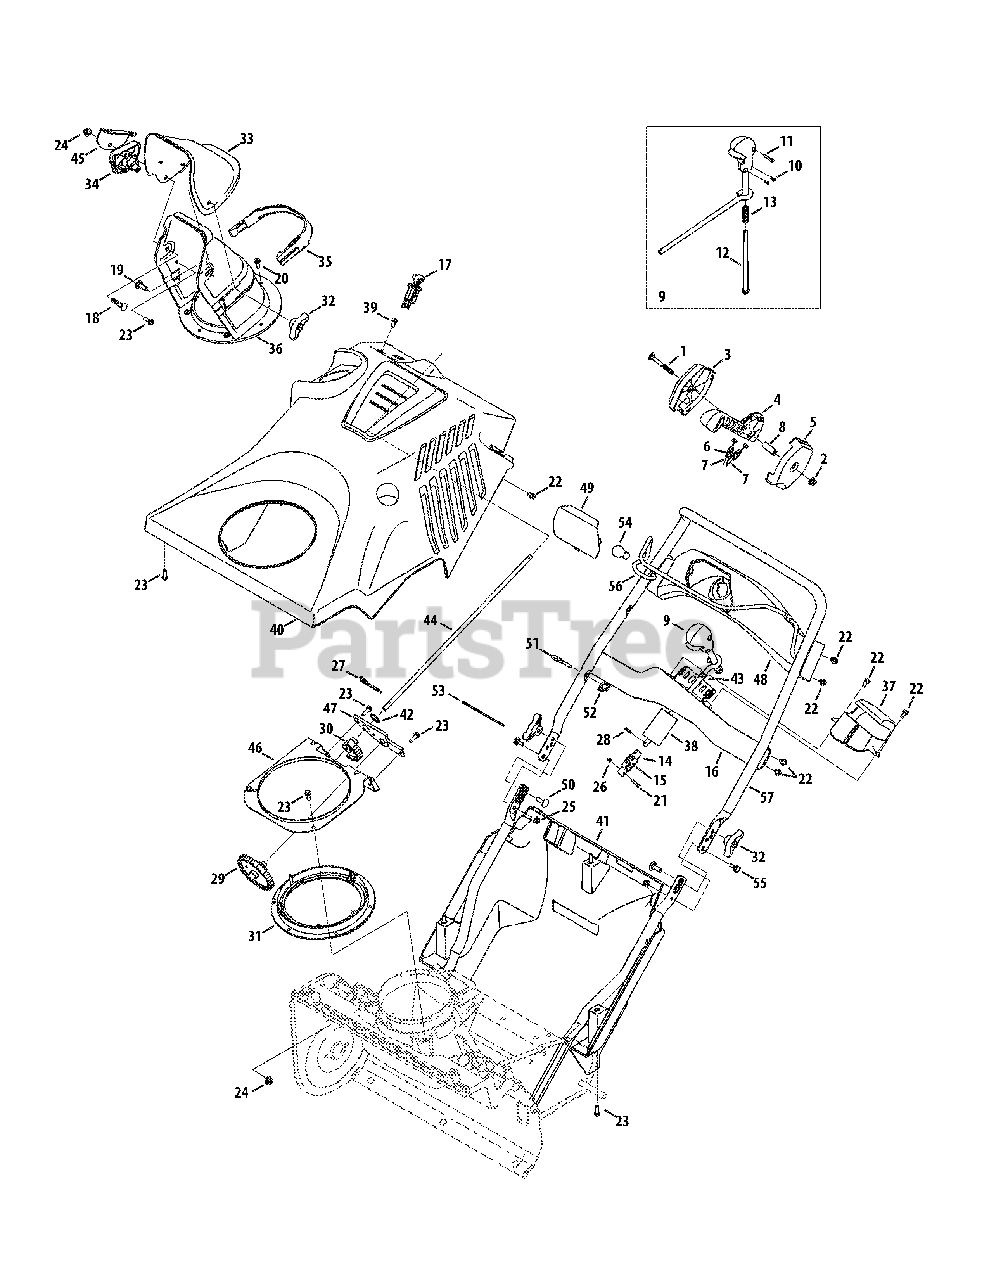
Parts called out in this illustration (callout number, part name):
1	Carriage Bolt, 5/16-18 x 2.5
2	Flange Lock Nut, 5/16-18
3	Chute Control Panel
4	Cable Handle Guide
5	Chute Control Panel, Inner
6	Cable Clip
8	Spacer, .325 ID x .496 OD x 1.34
9	Chute Control Assembly
10	Screw, #6 x .375
11	Screw, #8 x 1.00
12	Chute Rod
13	Spring, .460 OD x 1.469
14	Joint Block Assembly
15	Roll Pin, 3/16 Dia. x 1.1 LG.
16	Indicator Bracket Assembly
17	Ignition Switch Assembly
18	Carriage Bolt, 5/16-18 x 1.00
19	Carriage Bolt, 5/16-18 x .75
20	Hex Washer Screw, 1/4 x .750
21	Screw, #8-32 x .875
22	Hex Washer Screw, 1/4-20 x .625
23	Screw, Hi-Lo:1/4-15, 0.75
24	Flange Lock Nut, 5/16-18
25	Flange Lock Nut, 1/4-20
26	Hex Lock Nut, #8-32
27	Cotter Pin
28	Pin, .156 x .875
29	Bevel Gear, 40T/11T
30	Spur Gear, 35T
31	Bevel Gear, 95T
32	Wing Knob, 5/16-18
33	Upper Chute
34	Cable Guide
35	Chute Plug
36	Lower Chute
37	Chute Cover
38	Grip, 1.18 x 3.33
39	Hex Washer Screw, 1/4-15 x .50
40	Top Cover
41	Bottom Cover
42	Flat Washer, .75 x 1.00 x .06
43	Plastic Bushing, .380 ID
44	Chute Rod
45	Cable Bracket
46	Gear Retainer Bracket
47	Gear Mounting Plate
48	Handle Panel Assembly
49	Handle Panel Lens
50	Carriage Screw, 5/16-18 x 1.00
51	Eye Bolt, 1/4-20
52	Handle Knob, 1/4-20
53	Cable Tie
55	Shoulder Screw, .375 x .148 x 1/4-20
56	Auger Bail
57	Upper Handle
